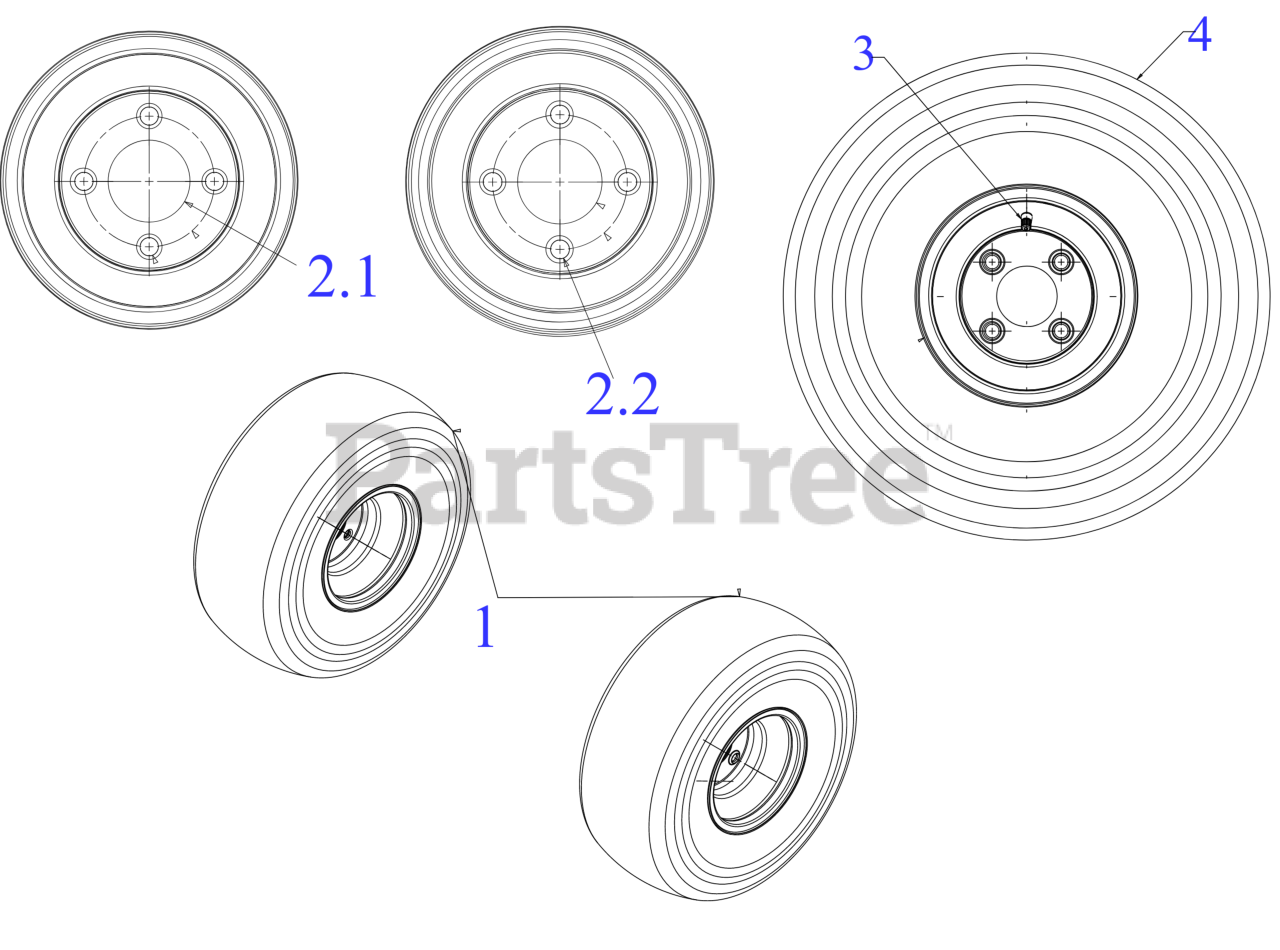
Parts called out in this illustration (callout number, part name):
1	COMPLETE WHEEL (20x8-8) TURFMASTR
1	COMPLETE WHEEL 20x8-8 (TURFMASTER)
2.2	REAR RIM ASSEMBLY
3	TUBELESS AIR VALVE
4	TIRE (20x8-8) TURFMASTR
